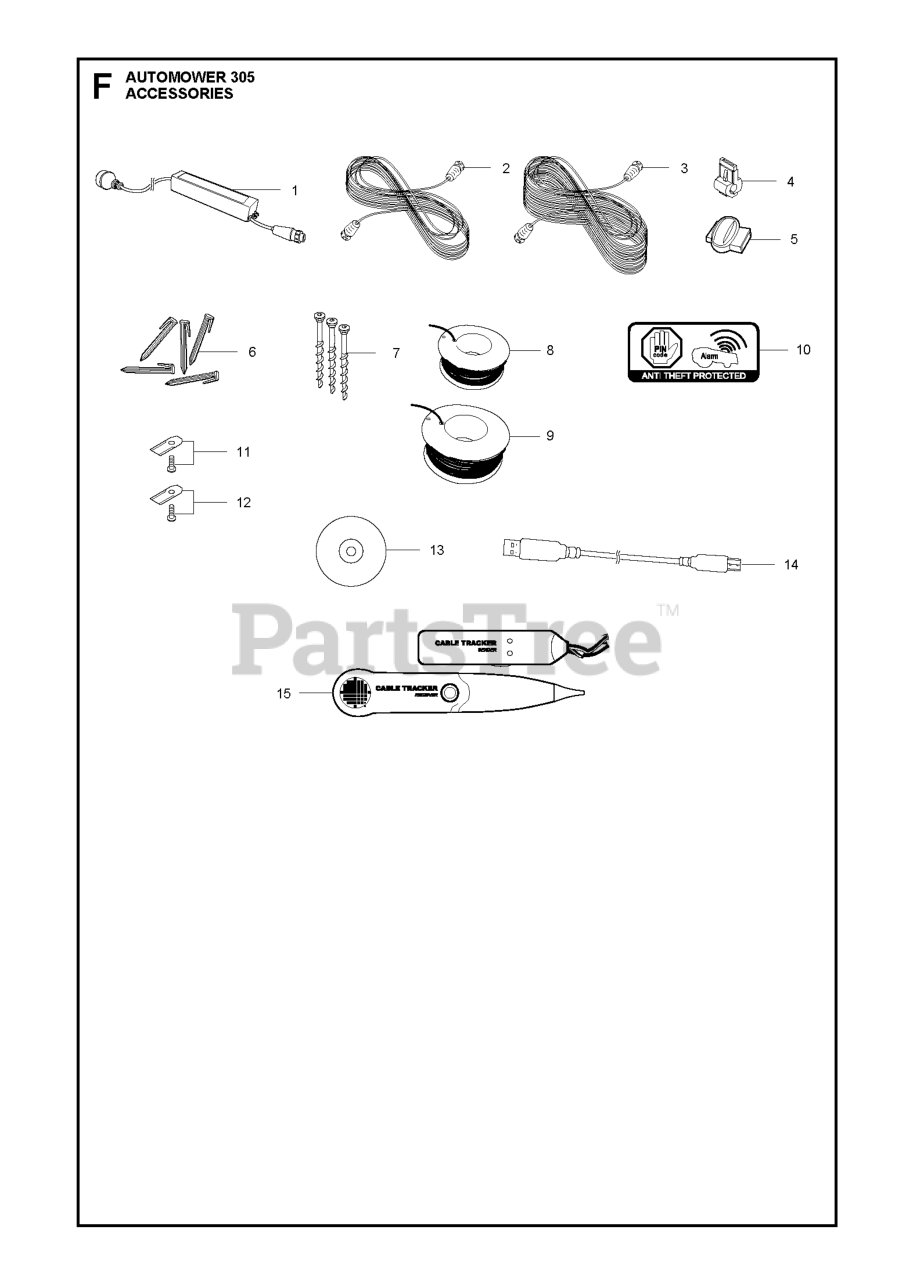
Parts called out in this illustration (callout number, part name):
4	BRAKER
5	SPLICE CONNECTOR 50 PCS/PK
5	SPLICE KIT
6	STAPLES (100 CT BAG)
7	SCREW KIT KIT INCLUDES THREE S
8	LOOP WIRE 150M
9	LOOP WIRE 250M
11	BLADE - 30 PCS
11	BLADE
11	BLADE - BULK PACK 500 PCS
12	BLADE CARBON STEEL, THICK BLAD
12	BLADE 9PCS EXTRA THICK
12	BLADE 300PCS -SINGLE HOLE THIC
15	TEST EQUIPMENT
